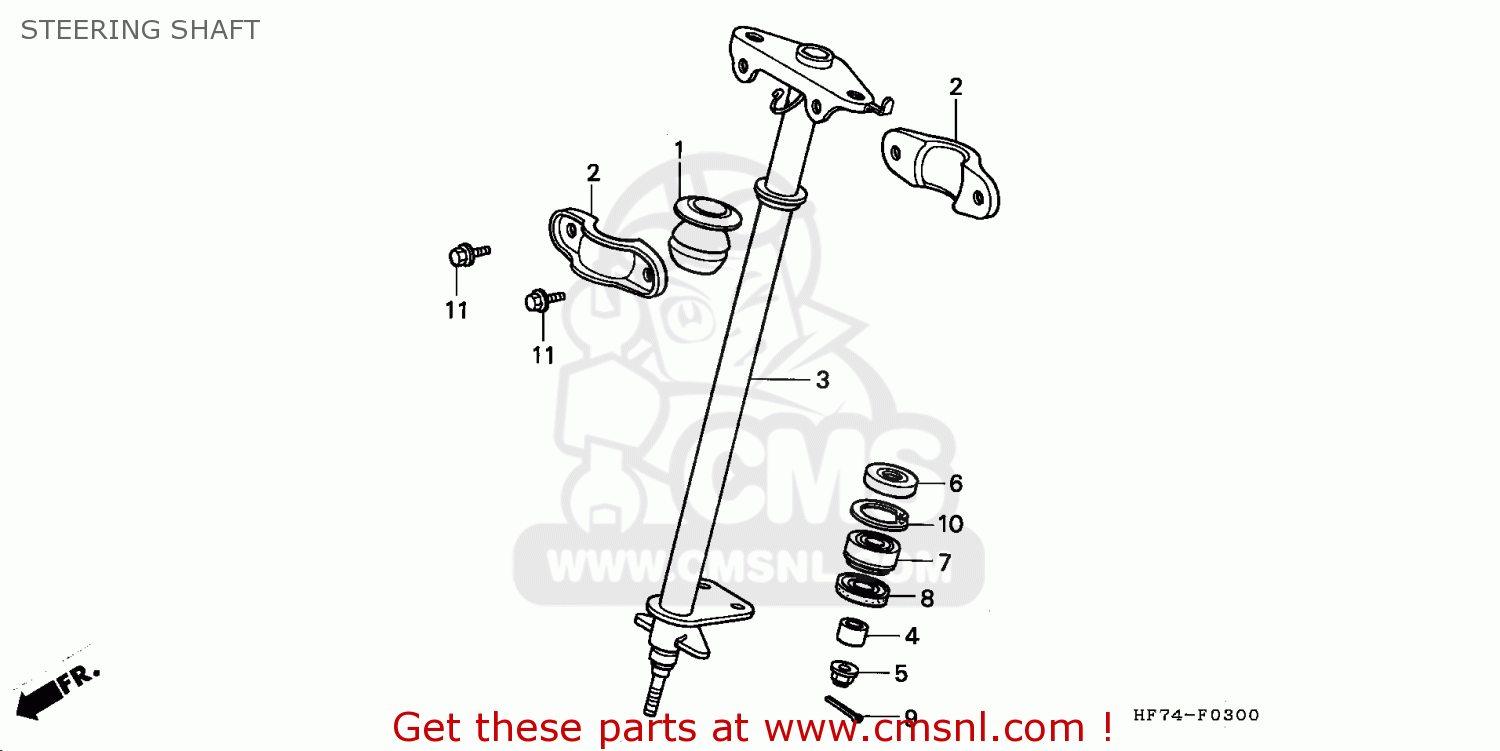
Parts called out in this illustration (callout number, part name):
1	BUSH,STEERING
2	HOLDER,STRG SHAFT
3	SHAFT COMP.,STEER
4	COLLAR,STRG.SHAFT
5	NUT,U,14MM
6	OIL.SEAL 27X40X6
7	BRG,BALL 17X40X12
8	SEAL,DUST,23X35X7
9	PIN,SPLIT,3X25
10	CIR CLIP,IN 40MM
11	BOLT,FLANGE,8X16
